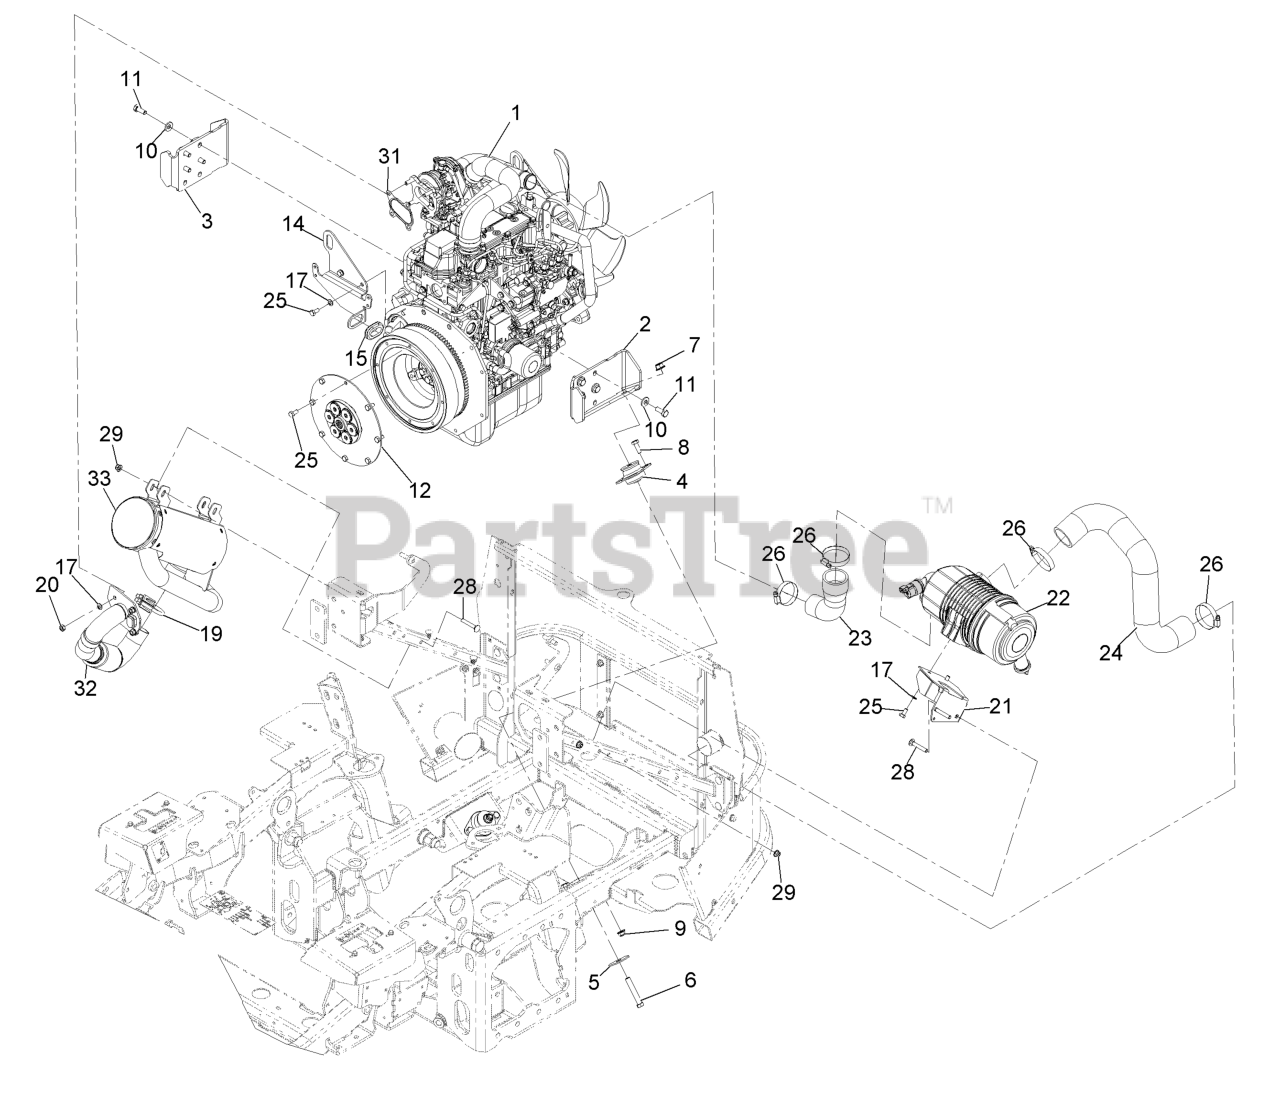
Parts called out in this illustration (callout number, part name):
1	Engine,Yanmar
2	Mount-Engine, Lt [black]
3	Mount-Engine, Rt [black]
5	Washer-Snubbing
6	Screw-HH
7	Nut-HF, NI
8	Screw-HH 3/8-16 X 1
9	Nut-Nyloc 3/8-16 Flg
10	Washer-Spring Disc 3/8
11	Screw-HH M10-1.5 X 35Mm
12	Flywheel Coupling ASM
14	Bracket-Guide
15	Grommet
17	Washer-Belleville
20	Nut-Hex M8-1.25
21	Bracket-Cleaner, Air
22	Air Cleaner ASM
23	Hose-Air
24	Hose-Air
25	Bolt
26	Clamp-Hose
28	Bolt-Carriage 3/16-18 X 2
29	Nut-Nyloc 5/16-18 Flg
31	Gasket-Header
32	Header Pipe
33	Muffler-ASM
